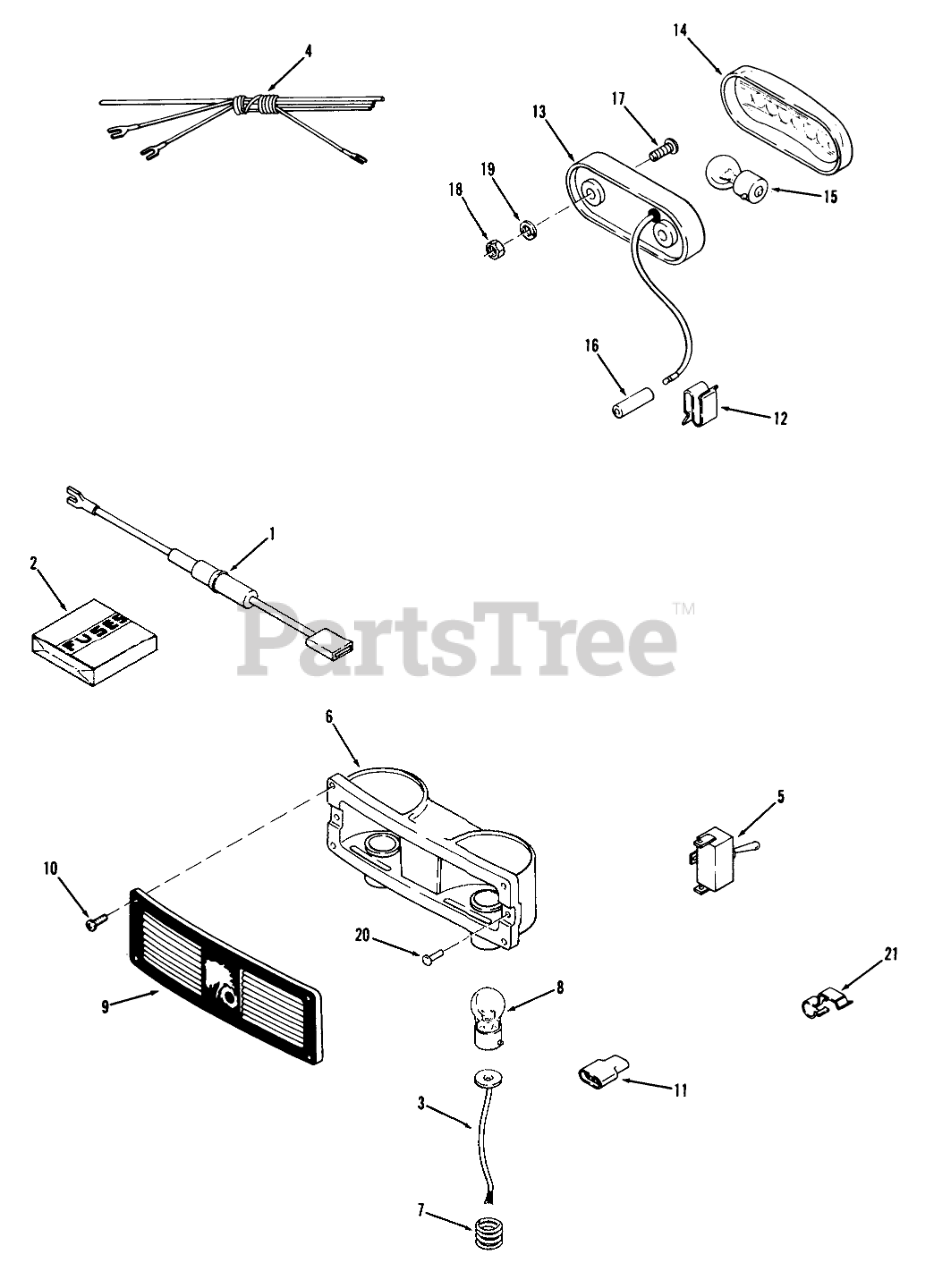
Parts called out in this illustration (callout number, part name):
1	ASSY FUSED CONNECTOR
3	WIRE ASSY
4	Wire Harness-Lights
5	SWITCH-LIGHTS
6	ASSY REFLECTOR HOUSI
7	SPRING
8	BULB
9	Lens
10	Pan HD Swage
11	CONNECTOR 3 WIRE
12	SPEED CLIP
13	Base-Taillight
14	Lens-Taillight
15	Bulb
16	CONNECTOR 2 WIRE
17	Screw
18	Nut
19	Lockwasher
20	RIVET
21	CLIP-WIRE
